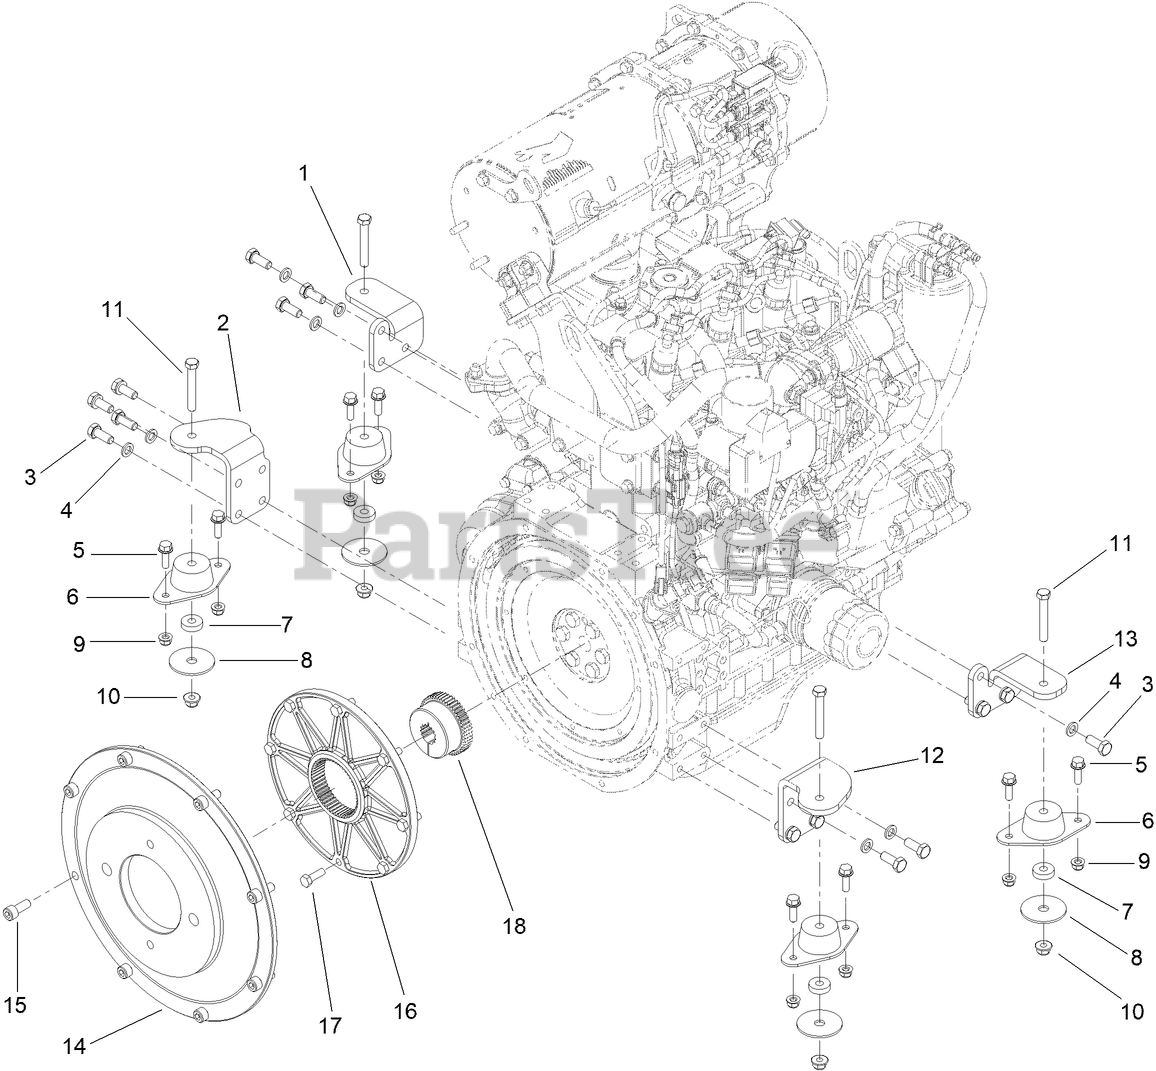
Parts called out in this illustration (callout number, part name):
1	ENGINE MOUNT
2	MOUNT-ENGINE, LH REAR
3	SCREW-HH
4	WASHER-LOCK
5	SCREW-HHF
6	MOUNT-ENGINE
7	SPACER
8	WASHER-SNUBBING
9	NUT-HF, NI
10	NUT-HF, NI
11	SCREW-HH
12	MOUNT-ENGINE, RH REAR
13	ENGINE MOUNT
14	PLATE - MOUNTING, PUMP
15	SCREW-HSH
16	FLANGE-FLYWHEEL
17	SCREW-HH
